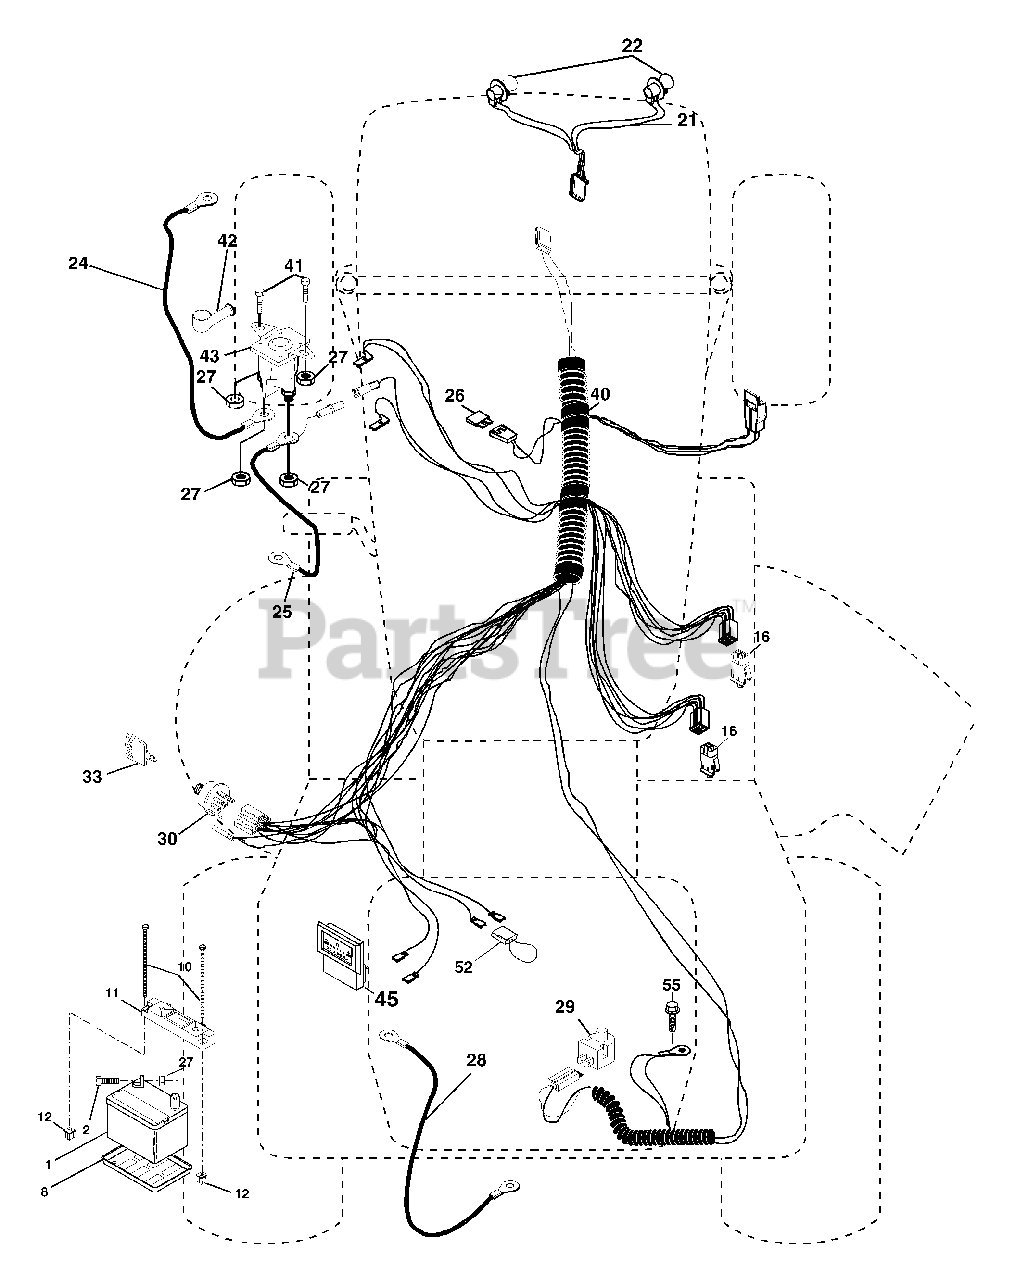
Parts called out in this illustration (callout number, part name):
1	Battery
2	Bolt Hex Hd 1/4-20 unc x 3/4
8	Tray Battery
10	Bolt 1/4-20 x 7.5
11	Hold down Battery Front Mount
12	Nut Push Nylon 1/4
16	Switch Interlock
21	Harness Asm Light W/4152j
22	Bulb Light #1156
24	Cable Battery 6 Ga. 11" red
25	Cable Battery 6 Ga. 22" red w/16 wire
27	Nut Keps Hex 1/4-20 unc
28	Cable Ground 6 Ga. 21" black
29	Switch Plunger Gray
30	Switch Ign Delta
33	Key Ign Molded Generic
40	Harness Ign.
41	Bolt Blk Fin Hex 1/4 - 20 x 1/2
42	Cover Terminal Red
43	Solenoid
45	Ammeter Rectangular 15 amp
52	Protection Wire Loop
55	Screw THDROL 5/16-18 x 1/2
